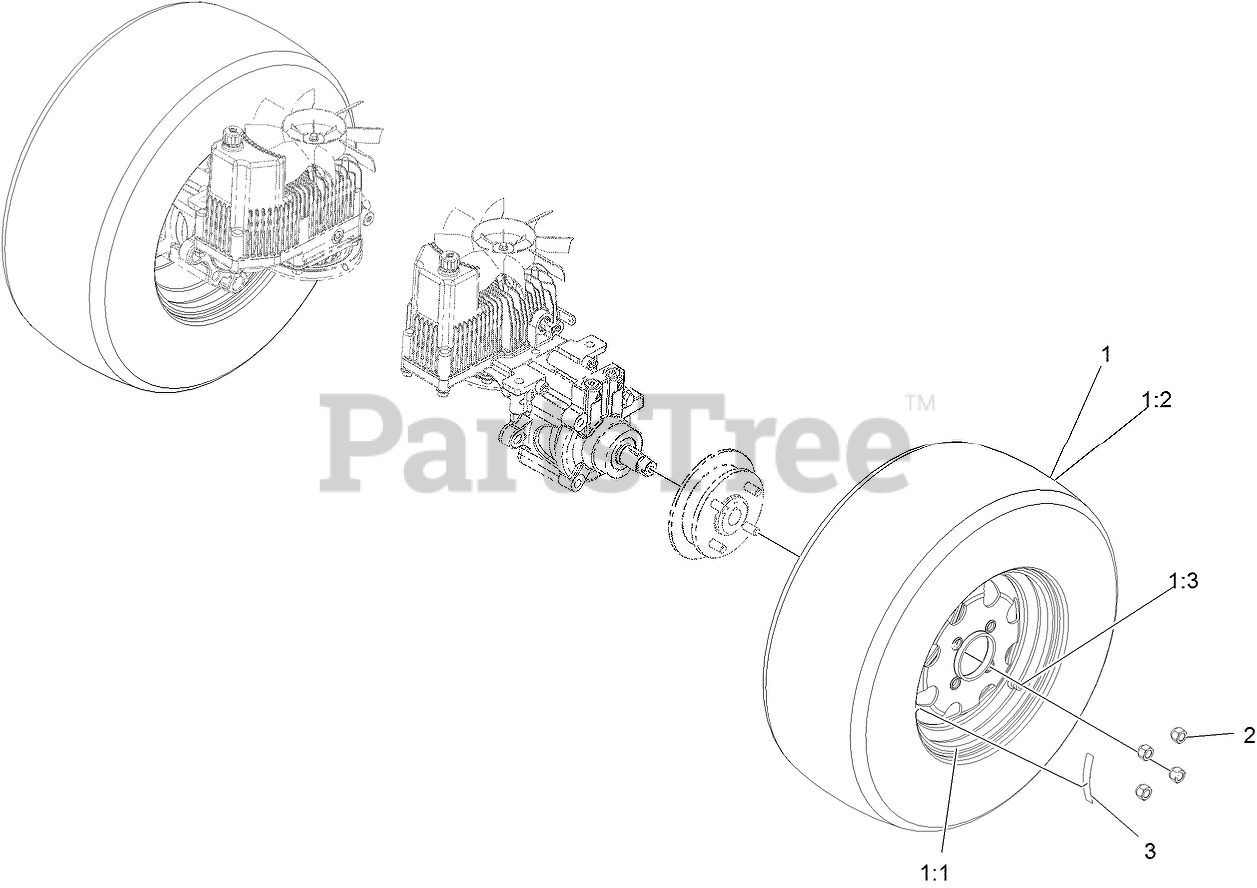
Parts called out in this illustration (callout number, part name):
1	WHEEL AND TIRE ASM
1:1	RIM ASM
1:2	TIRE
1:3	Stem-Valve
2	NUT-LUG
3	DECAL-TORQUE, WHEEL HUB LUG
